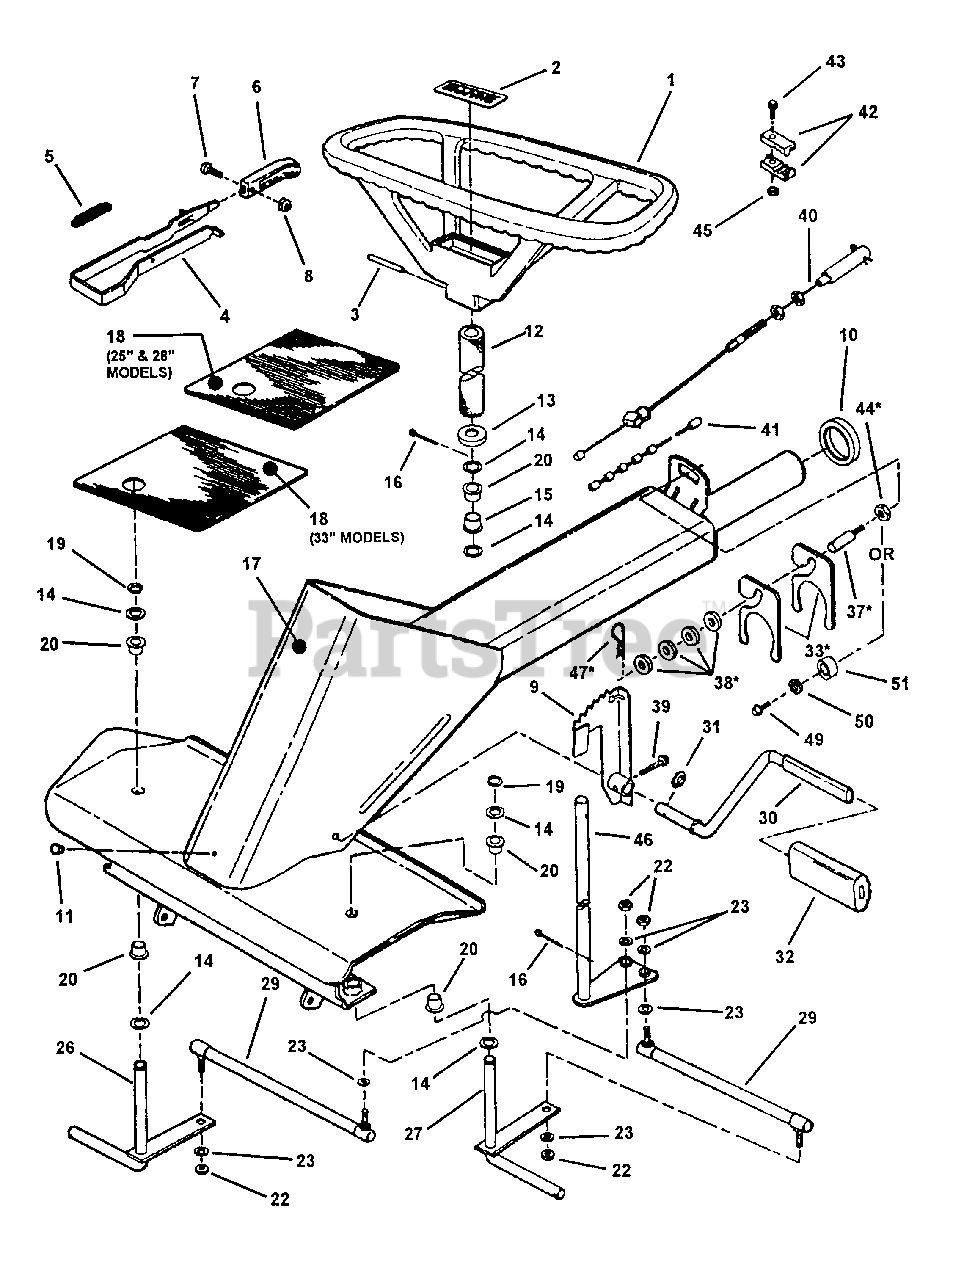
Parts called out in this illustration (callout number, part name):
1	ASSEMBLY, Steering Wheel
2	LOGO, SNAPPER
3	PIN, 1/4 x 1-1/2" Roll
4	LEVER, Clutch/Brake
5	SPRING
6	GRIP, Lever
7	SCREW, #8-32 x 3/8" Cross Recess
8	NUT, #8-32 Hex
9	ARM, Clutch/Brake
10	SPACER, Main Tube
11	FASTENER/PLUG, Panel
12	COVER, Steering Shaft (Foam)
13	COVER
14	WASHER, 3/4 Flat
15	BUSHING, 3/4" Steering Shaft
16	COTTER-PIN, 3/16 x 1-1/2"
17	FRAME, Front (Narrow, 16" @ King Pin Holes)
17	FRAME, Front (Wide, 19" @ King Pin Holes)
18	PAD, Foot (Right Side)
19	RING, 5/8" Ext. Retaining
20	BEARING, Nylon
22	NUT, 5/16-24 Hex
23	WASHER, 5/16 Split Lock
26	PIN, Wide King (Right Side)
27	PIN, Wide King (Left Side)
29	TIE-ROD 9.13"
30	PEDAL, Clutch/Brake
31	RING, 5/8" External Retaining
32	PAD, Clutch/Brake Pedal
33	* SPACER, Pivot (25" Deck)
37	* STUD, 3/8-24 x 5/8" Shoulder (25" Deck)
38	* SPACER (25" Deck)
39	SCREW, 5/16-18 x 1-1 /4" Hex Washer Self-Tapping
40	CABLE, Brake (Snap-in)
41	CABLE, Clutch 48.71" Long
42	UNION, Cable
43	BOLT, 1 /4-20 x 3/4" Hex Flange Lock
44	* NUT, 3/8-24 Hex Nyloc (25" Deck)
45	NUT, 1/4-20 Hex Center Lock
46	SHAFT, Steering (Wide Front End)
47	HAIRPIN, 1/8 x 2-9/16" (25" Deck)
49	SCREW, 3/8-16 x 5/8" Self-Tapping
50	WASHER, 3/8" Flat
51	SPACER, .39 x .625 x .19
